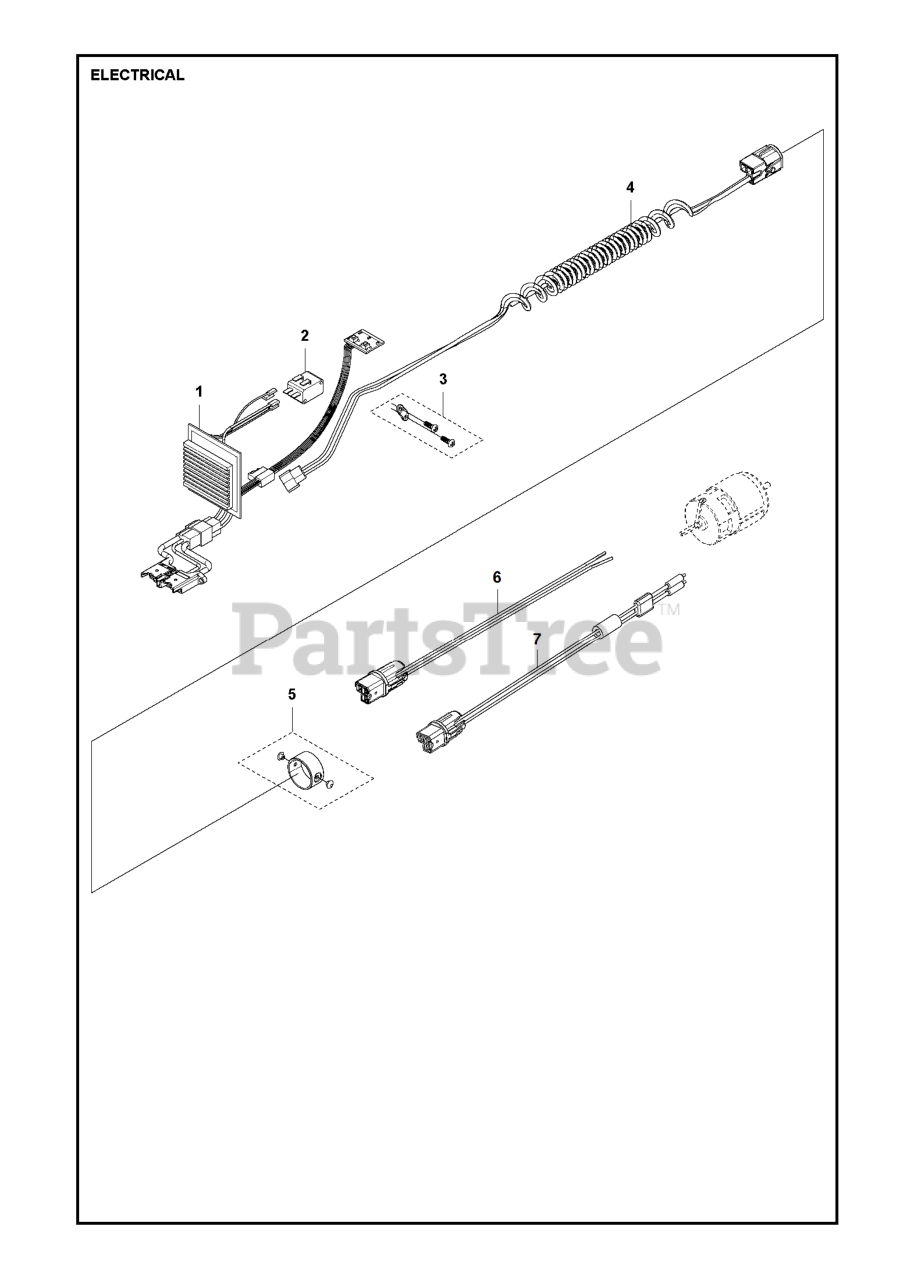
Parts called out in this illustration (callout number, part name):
1	CONTROL UNIT ASSY
2	SWITCH ASSY
3	PRESSURE PLATE ASSY
4	CABLE ASSY SPIRAL
5	RING FIXING
6	CONNECTOR ASSY
